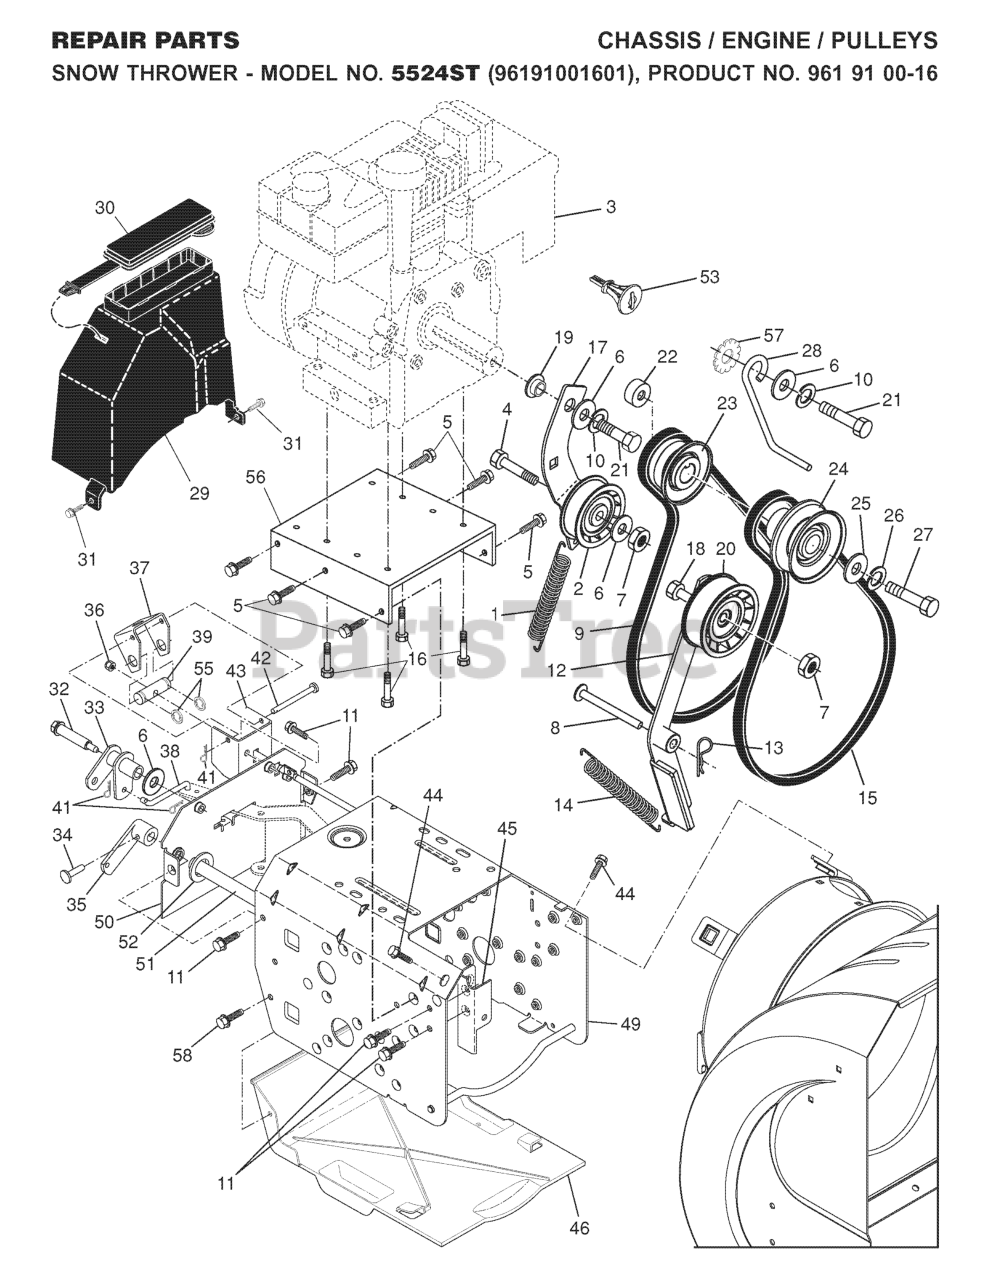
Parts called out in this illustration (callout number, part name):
1	STEERING WHEEL
2	FRONT AXLE ASSY
3	SPINDLE ASM LH
4	SPINDLE ASM RH
5	THRUST WASHER
10	LINK.DRAG.DROPPED.LT
11	WASHER, LOCK 3/8
13	BEARING.FRT.SPACER.AXLE
15	NUT-LOC,FLANGE LT
17	SHAFT ASM STEERING
18	THRUST WASHER
19	STEERING SHAFT SUPPORT
22	SCREW.HX.WSH.HD
23	SHAFT ASSY PITTMAN
25	BRACKET STEERING
27	GEAR.SECTOR
29	SCREW
32	ROD ASSY/TIE BALL
36	BUSHING, STEERING
37	SCREW.TT.#10-32X.5.3/8.FLANGE
38	INSERT,STR WHEEL
39	WASHER T
40	GRIPCO NUT
41	ADAPTER LT
42	BOOT, STEERING
44	EXT SHAFT STEERING
46	CAP.SPINDLE.BLACK
47	ZERK M
51	NUT.71038.31-18.HEX.NYLOCK
54	BOLT.5/16-18X1-1/4 FULL.THREAD
62	STEERING KIT
65	SPACER AXLE
66	BEARING ARM
67	Bolt, Hex 5/8 -11 x 2 - 3/4 Gr. 5
68	AXLE, BRACE
74	JOINT
76	TIE ROD
79	WASHER
80	BOLT.HX.NYLON3/8-16X
